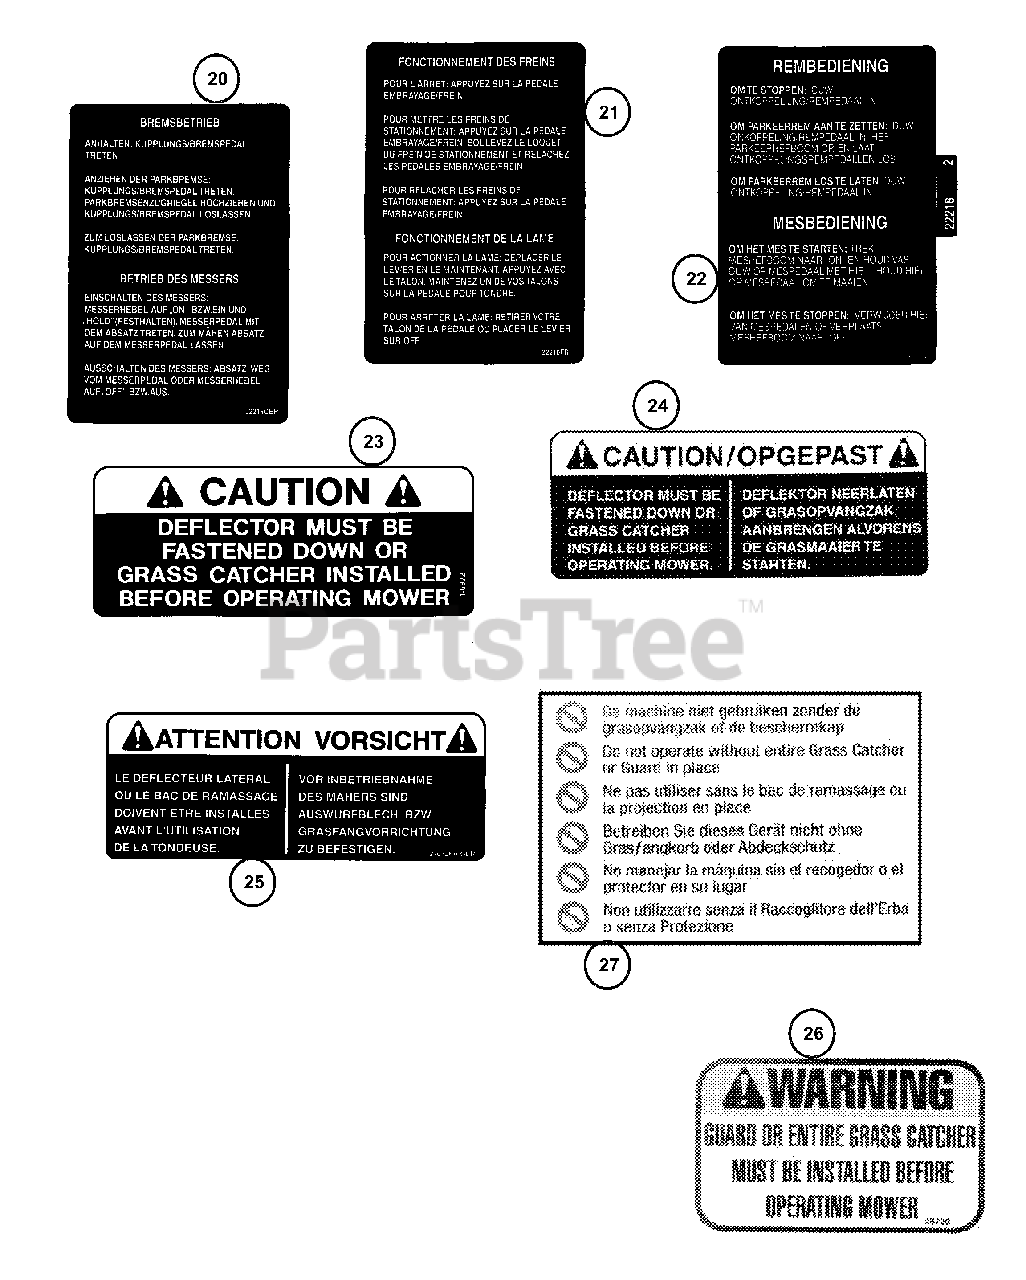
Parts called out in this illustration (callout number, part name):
20	DECAL, Brake Operation (Germany)
21	DECAL, Brake Operation (French)
22	DECAL, Brake Operation (Dutch)
23	DECAL, Deflector Instruction
24	DECAL, Deflector Instruction (English/Dutch)
25	DECAL, Deflector Instruction (French/German)
26	DECAL, Chute/Deflector Warning
27	DECAL, Chute/Deflector Warning (International)
